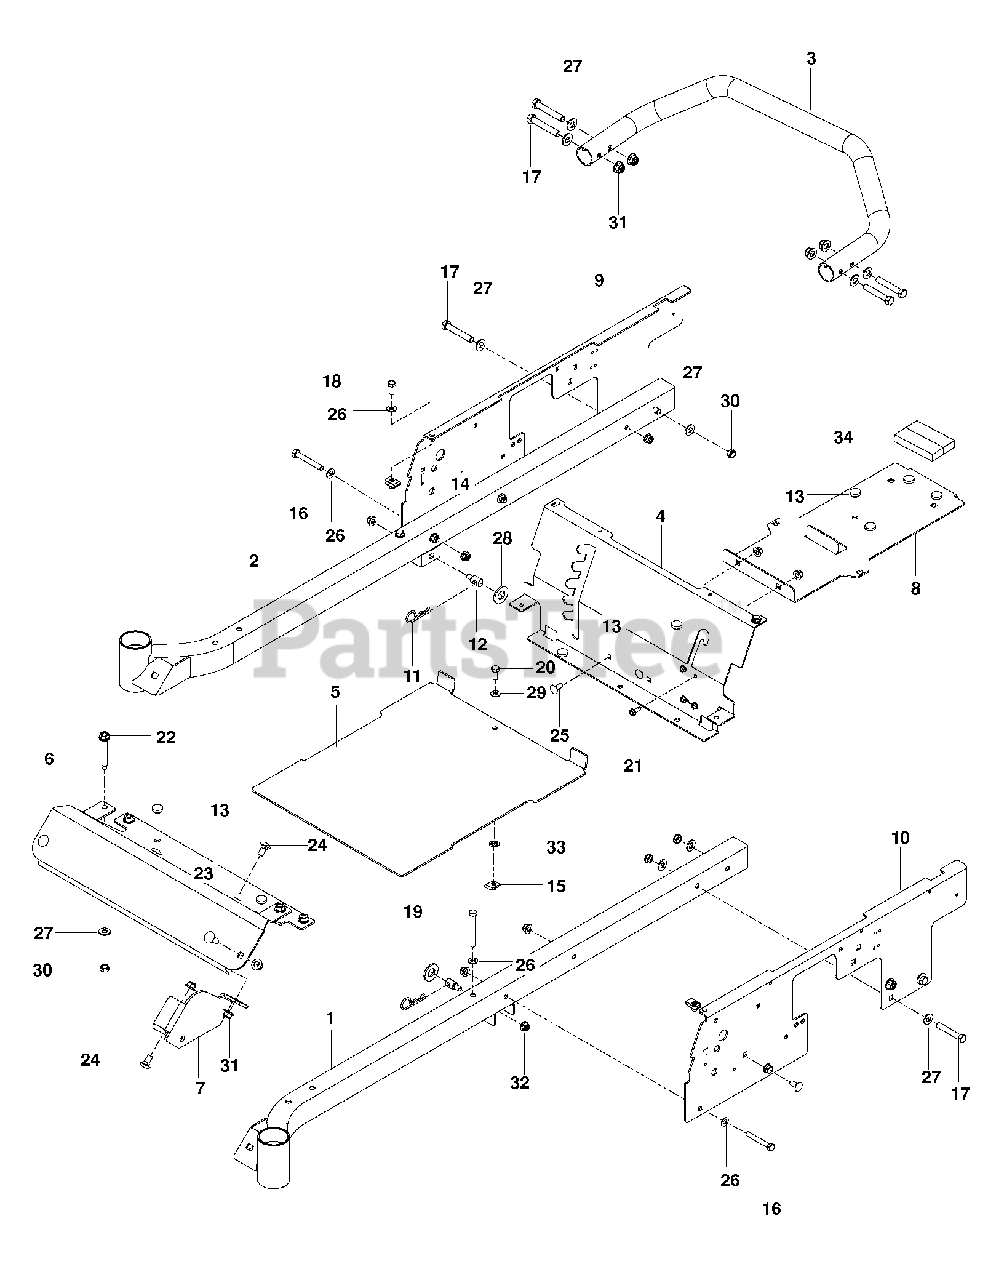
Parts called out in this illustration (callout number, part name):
1	FRAME, TUBE, LH, BLUE
2	FRAME TUBE, RH, BLUE
3	IMPACT BAR, BLUE
6	FOOT REST, BLUE
7	BRACKET, FRONT DECK, BLK
8	SUPPORT, TANK/BATT, BLK
9	PLATE, RH SIDE, BLUE
10	PLATE, LH SIDE, BLUE
11	HAIRPIN #4
12	STUD.FASTNER.W/ANTI-ROTATE
13	GROMMET, BUMPER
14	U-CLIP 5/16-18 NUT RETAINER
15	1/4-20 U NUT
15	HCS 1/4C X 3/4 HCS
16	CAPSCREW
17	HCS 3/8C X 2 1/4
18	HCS 5/16C X 3/4
19	HCS 5/16C X 2-3/4
20	HCS 5/16-18X2
21	SCREW 1/4 X 5/8
22	ENGINE BOLT, SPECIAL
23	RHSNB 3/8C X 1
24	RHSNB 3/8-16 X 3/4 GR5 ZD
25	BOLT 5/16C X 3/4" CARRIAGE
26	FLAT WASHER 5/16 SAE
27	WASHER 3/8 SAE FLAT
28	WASHER 5/8 FLAT
29	WASHER 1/4 SAE
30	NUT HEX 3/8-16 NYLON, THIN
31	NUT 3/8-16 HEX FLG NYLOC ZD
32	5/16-18 NYLOC FLANGE NUT
33	PALNUT 1/4
34	FOAM STRIP, FUEL TANK
